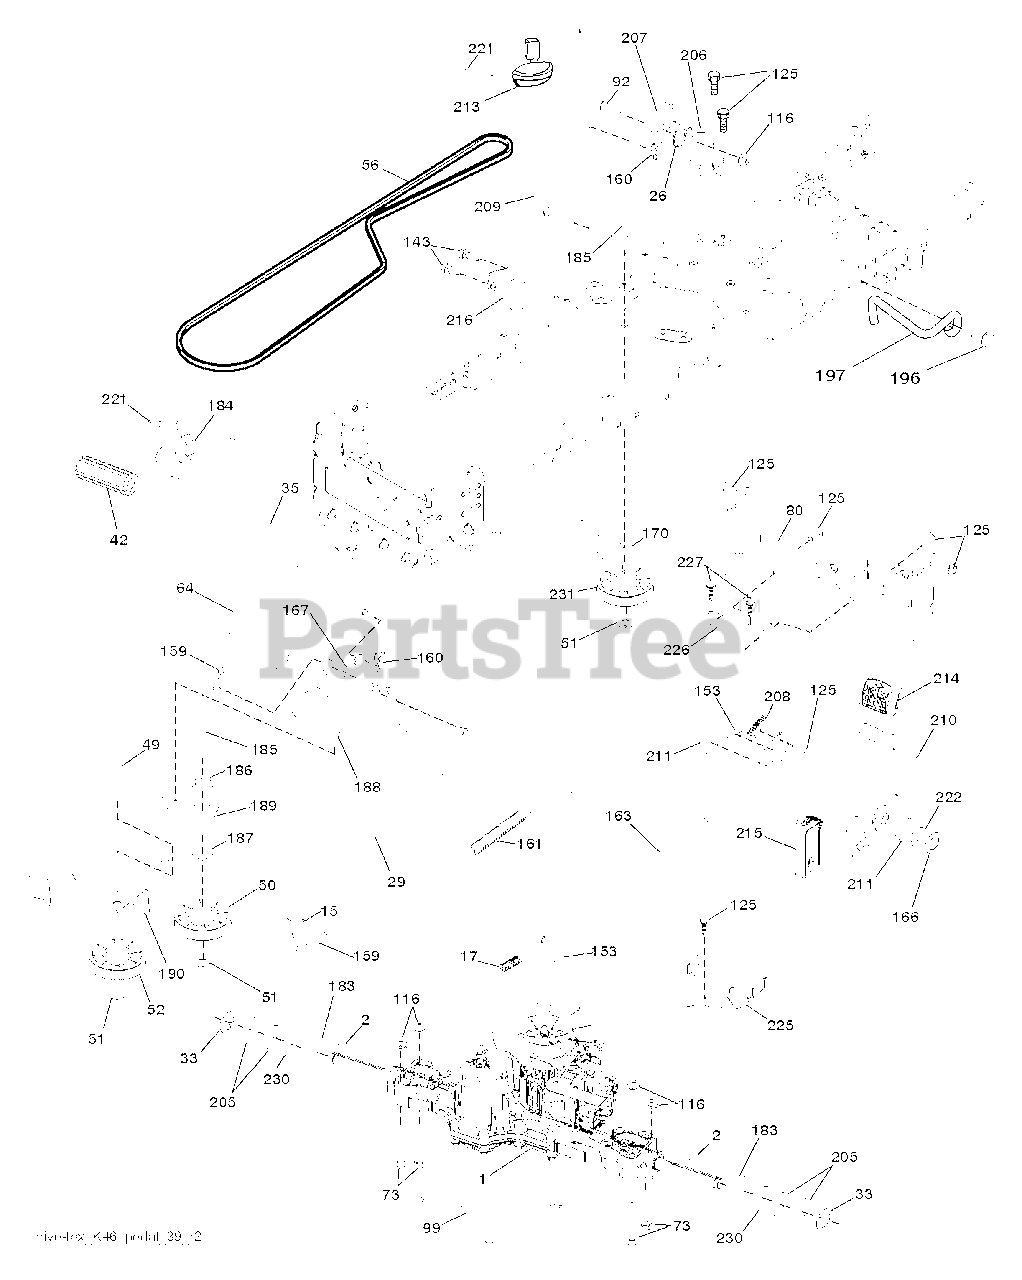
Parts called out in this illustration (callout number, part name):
2	SQUARE KEY
15	WASHER
17	SPRING.BRAKE.K46.GREEN
26	SPRING.RETURN.CRUISE
29	ROD.BRAKE.K46
35	ROD.BRAKE.PARTK.HUSQ.TEX
42	PEDAL COVER T
50	IDLER.FLAT.910.OFFSET
51	NUT LOCK FLG 3/8-16 UNC
52	IDLER.V-GROOVE.910.OFFSET
56	V-BELT.MOWER.92.40.42/K46
64	SHAFT.ASM.PEDAL.BRK.CNTR
80	STRAP.TORQUE.K46.K57R.TT
92	BOLT
99	ROD.SPRING.BYPASS.K46.LT.Z
116	NUT LOCK HEX FLANGE 5/16-18
125	SCREW
143	SCREW LT
153	RETAINER M
159	COTTER PIN
160	RETAINER CLIP
161	SPRING, RETURN LT
163	ROD.CONTROL.K57R.K46
166	NUT.PUSH.625
167	LATCH.BRAKE.SPRING
170	KEEPER.CENTER SPAN.1.688
183	SPACER AXLE
184	RB HANDLE.PARKG.BRK.HUS/PRED
186	SPACER.RETAINER
187	WASHER 12/32X2X10GA
188	RP LINK.CLUTCH.GROUND.DRIVE
189	BELLCRANK.GROUND.DRIVE.TEX.
190	KEEPER.BELLCRANK.DRIVE
196	SCREW 3/8-16X1
197	LINK.CLUTCH.ANIT-ROTAT
206	BRKT.MOUNT.LATCH.CRUIS
207	LATCH.CONTROL.CRUISE
208	GEAR.SECTOR.CONTROL.CR
209	ROD.CONTROL.CRUISE.GT.
210	ROCKER.ASM.PEDAL.CONTR
211	BEARING.NYLON
213	KNOB.CONTROL.CRUSIE.HU
214	PEDAL.FORWARD.PAD.TEX
215	PEDAL.REVERSE.TEX.GT.4
216	BRACKET.PULLEY.IDLER.W/TEX
221	RETAINER.SPRING.CLIP.H
222	WASHER 21/32 X 1-1/4 X 10 GA.
225	KEEPER.BELT.TRANSAXLE.K46
226	BRACKET.MOUNT.TORQUE.K46.TLT
227	SCREW
230	WASHER.HARDENED
231	IDLER.V-GROOVE.1.688.OFFSET
